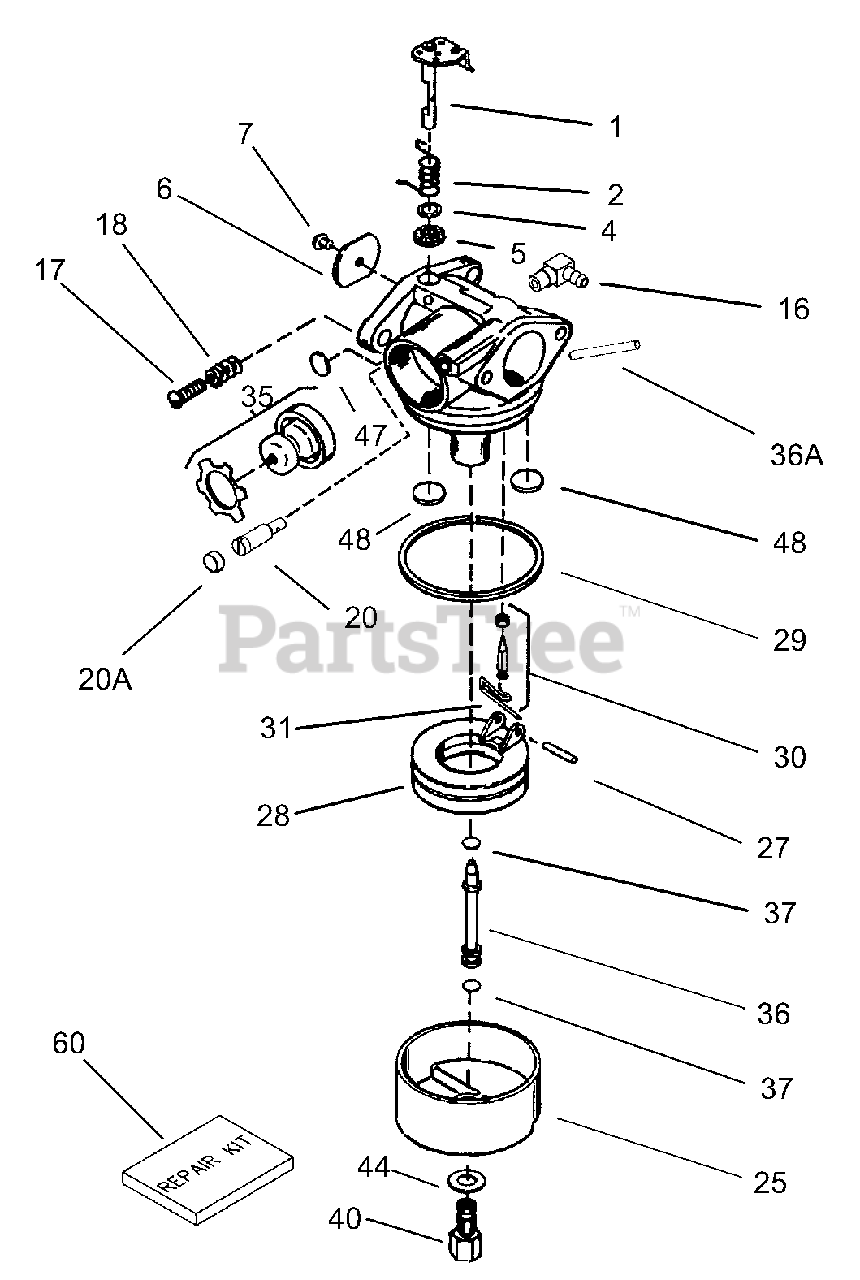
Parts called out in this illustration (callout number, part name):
1	Throttle Shaft & Lever Assembly
2	Throttle Return Spring
4	Dust Seal Washer
5	Dust Seal
6	Throttle Shutter
7	Shutter Screw
16	Fuel Fitting
17	Throttle Crack Screw/Idle Speed Screw
18	Tension Spring
20	Idle Restrictor Screw
20A	Idle Restrictor Screw Cap
25	Float Bowl
27	Float Shaft
28	Float (Plastic)
29	Float Bowl O-Ring
30	Inlet Needle, Seat, & Clip (Incl. 31)
31	Spring Clip
35	PrimerBulb (Red)/Retainer Ring
36	Main Nozzle Tube
36A	Bowl Vent Tube Extension
37	O-Ring, Main Nozzle Tube
40	High Speed Bowl Nut
44	Bowl Nut Washer
47	Welch Plug, Idle Mixture Well
48	Welch Plug, Atmospheric Vent
60	Repair kit (Incl. Items Marked in Notes)
